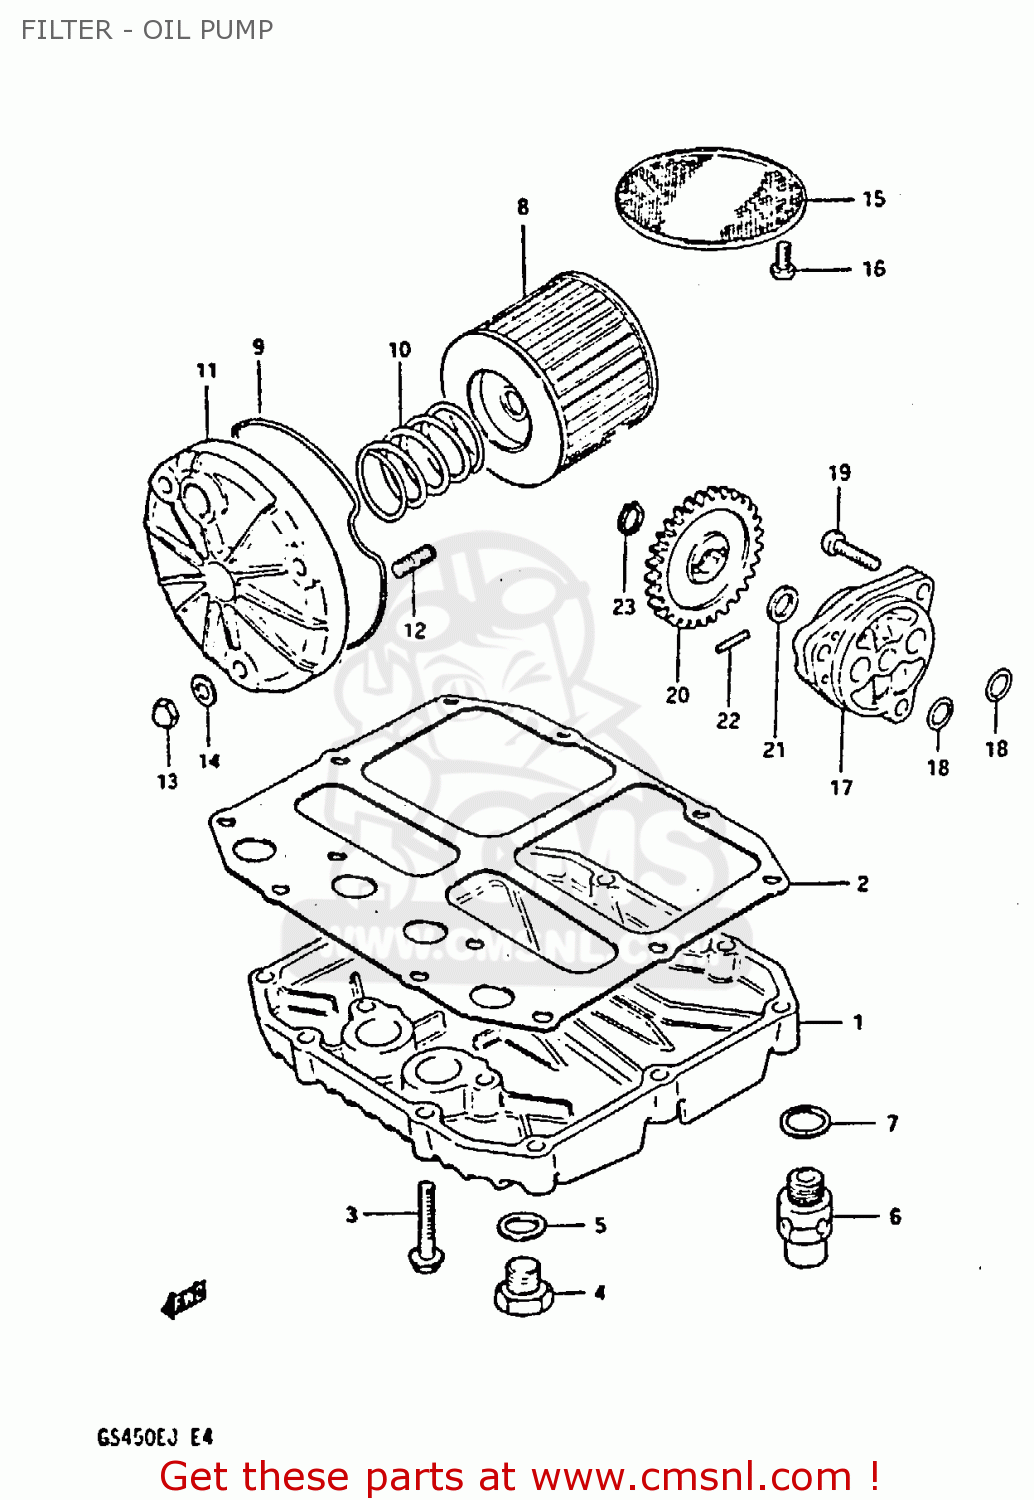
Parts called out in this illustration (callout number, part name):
1	PAN,OIL
2	GASKET,OIL PAN (MCA)
3	BOLT 6X30
4	PLUG
5	GASKET(14X19.2X2) (NAS)
6	VALVE ASSEMBLY,OIL RELIEF
7	WASHER
8	FILTER ASSY,ENGINE OIL
9	O RING,OIL FILTER CHAMBER CAP
10	SPRING
11	CAP,OIL FILTER
12	STUD 6X20
13	NUT 6MM
14	WASHER
15	STRAINER,ENGINE OIL
16	SCREW 6X12
17	PUMP ASSY,ENGINE OIL
18	O RING(D:1.9,ID:13)
19	SCREW
20	GEAR,OIL PUMP DRIVEN
21	SHIM
22	PIN(4X15.8)
23	CIRCLIP
